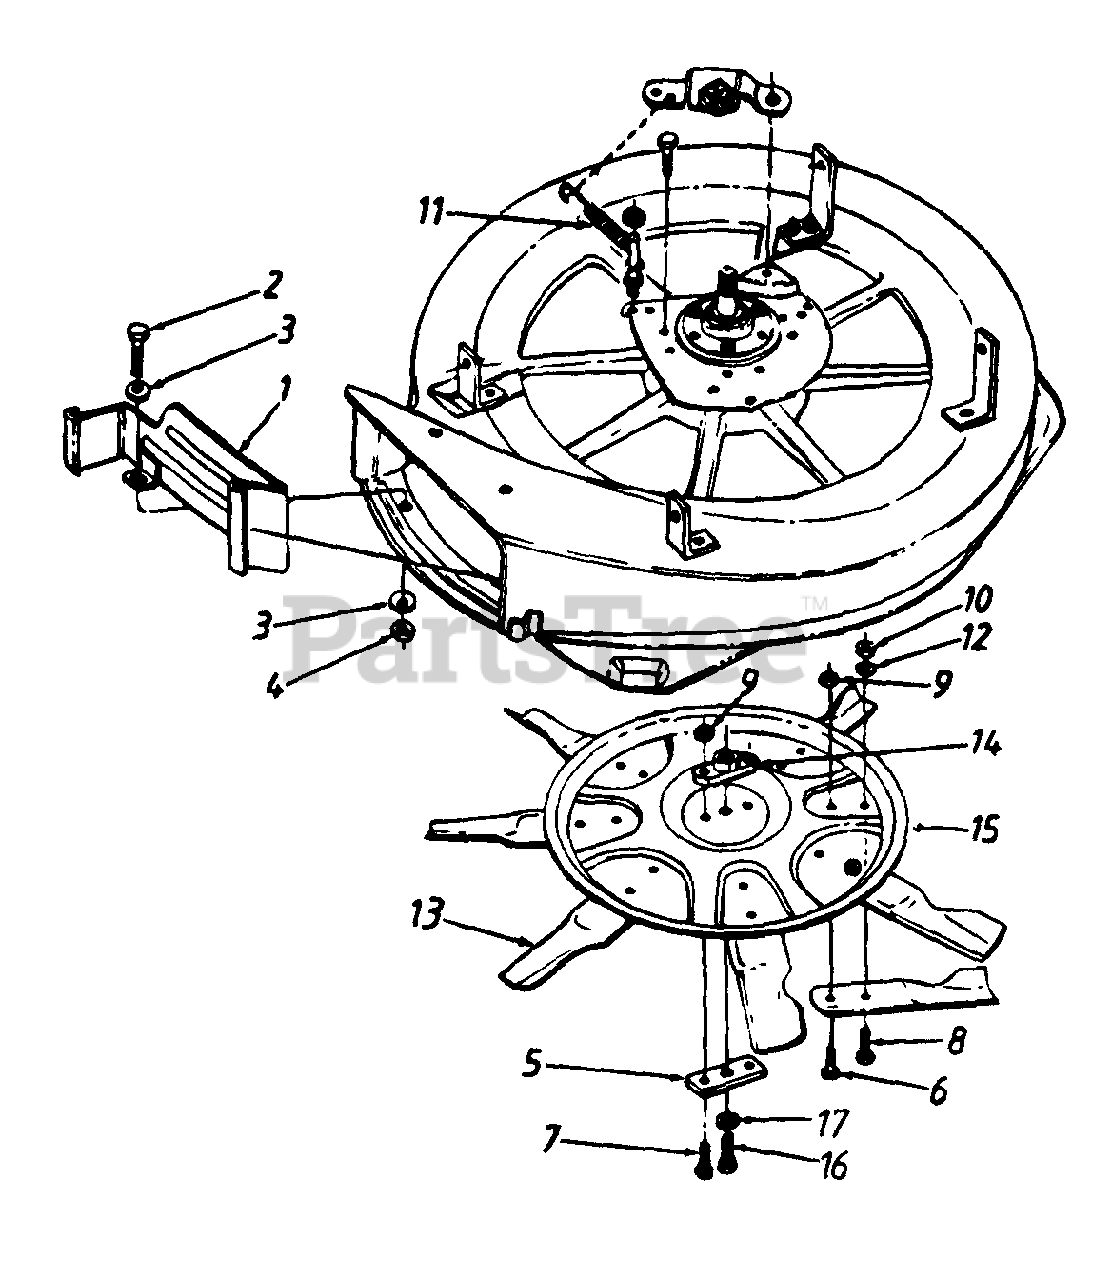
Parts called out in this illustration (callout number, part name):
1	Mulching Baffle Ass'y.
2	Hex Bolt 5/16-18 x .5"
3	Bell-Wash. .325" I.D.
4	Hex L-Nut 5/16-18 Thd.
7	Hex Bolt 5/16-24 x 1.25" Lg. (Gr 5)
8	Hex Bolt 3/8-24 x .88" Lg.
9	Hex L-Nut 5/16-24 Thd.
10	Hex L-Nut 3/8-24 Thd. (Gr. 5)
11	Extension Spring 3.2" Lg.
12	Fl-Wash .406" I.D. x 75"
13	30" Mulching Blade Tip
14	Blade Adapter
15	30" Mulching Blade Disc
16	Hex Bolt 3/8-24 x 1.25" Lg. (Gr. 8)
17	L-Wash 3/8" I.D.
